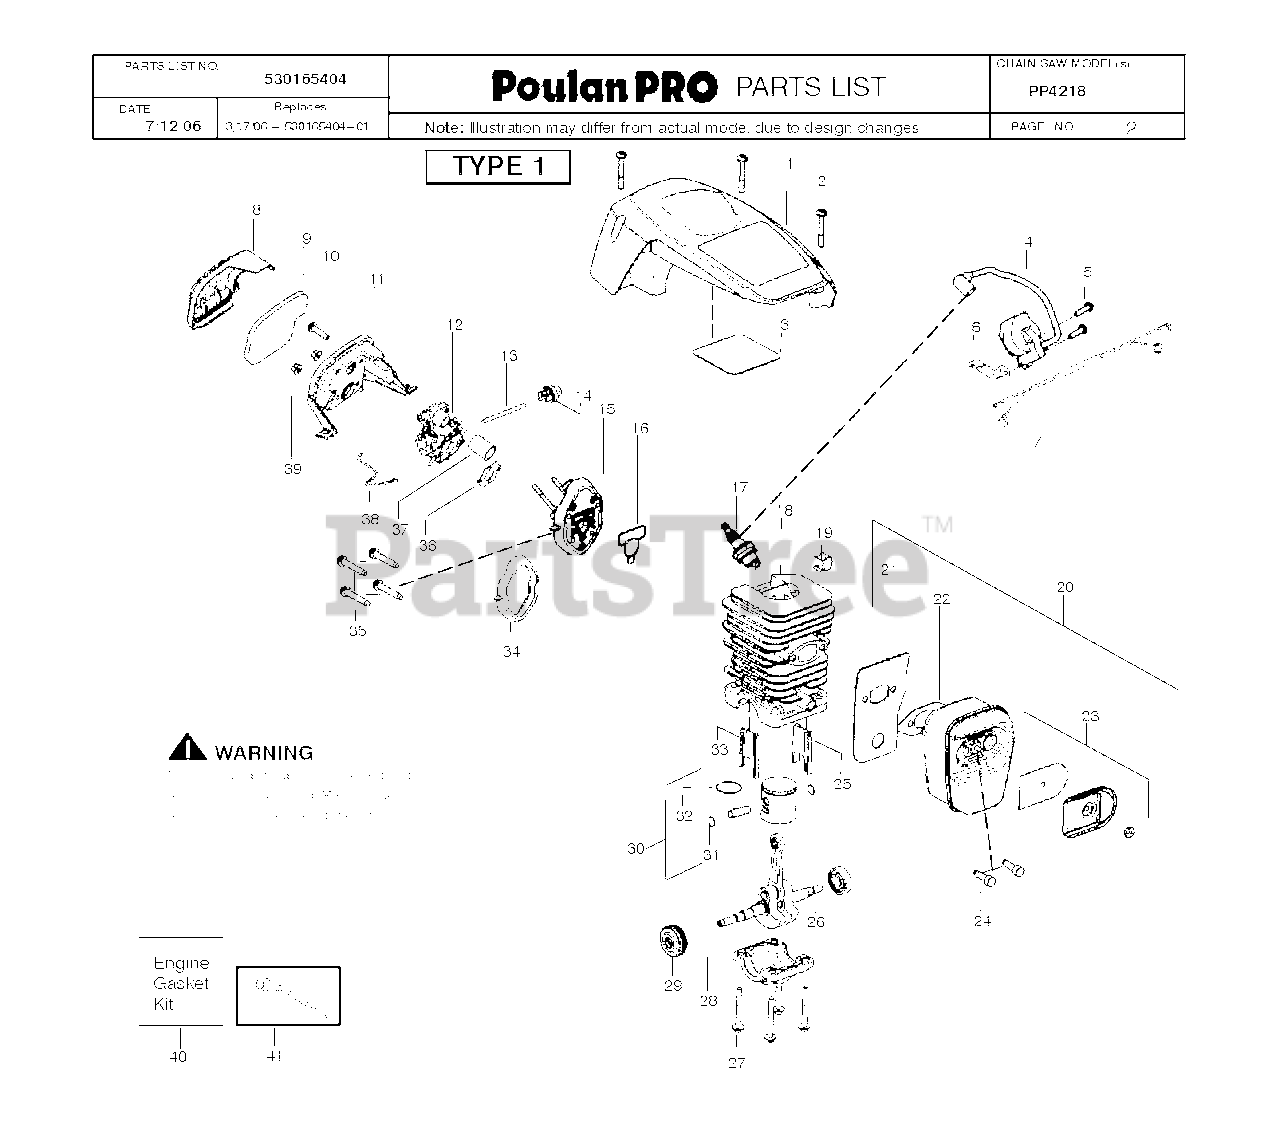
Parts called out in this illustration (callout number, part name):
1	SHIELD CYLINDER BLACK
3	TAPE REFLECTOR
5	SCREW M5.38-14X22.225MM
6	GROUND STRAP
7	ASSY WIRE HARNESS
8	COVER, AIR FILTER
9	FILTER AIR
10	SCREW M5-0.8X16
11	HSG FILTER
12	Poulan TBD
12	CARBURETOR
13	KIT-LINE
14	AIR PURGE
15	KIT CARB ADAPTOR
16	KIT GASKET SAS
17	SPARK PLUG (RCJ-7Y)
18	KIT CYLINDER
19	CLIP-HIGH TENSION LEAD
20	KIT MUFFLER
21	PLATE BACK MUFFLER
22	KIT GASKET SAS
23	KIT SPARK ARRESTOR
24	SCREW MUFFLER
25	INSERT TRANSFER PORT LEFT
26	ASSY CRANKSHAFT AND ROD
27	BOLT M6-1.0 X 25MM
28	CRANKCASE CASTING
29	BEARING & SEAL ASSEMBLY
30	KIT PISTON
31	C-CLIP,PSTN PIN 36/41
32	RING-PISTON
33	INSERT TRANSFER PORT RIGHT
34	KIT GASKET SAS
35	SCREW M5-0.8X30MM
36	KIT GASKET SAS
37	TUBE INTAKE
38	WIRE THROTTLE
40	KIT GASKET SAS
41	WRENCH-BAR
